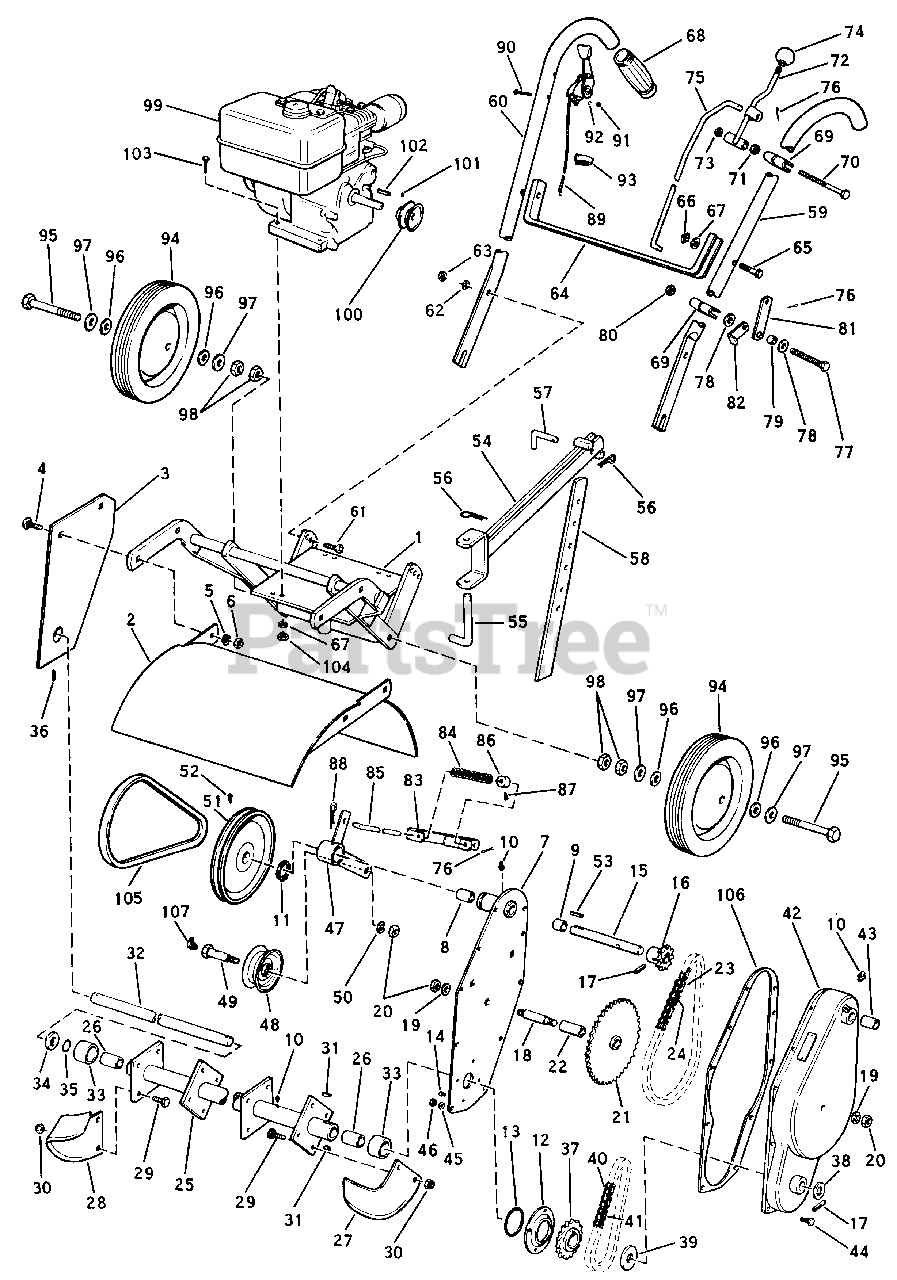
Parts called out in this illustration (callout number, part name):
1	Frame Assy.
2	Hood Assy.
3	Side Plate Assy.
4	Carriage Bolt 3/8-16 x 1 Lg.
5	Lockwasher 3/8
6	Hex Nut 3/8-16
7	Back Plate Assy.
8	Bushing
9	Bushing
10	Grease Fitting 1/4-28 St.
11	Snap Ring
12	Oil Seal Retainer
13	"O" Ring (Neoprene)
14	Self Tapping Screw #8-32 x 1/4 Lg.
15	Input Shaft
16	Input Sprocket & Hub Assy.
17	Roll Pin 3/16 x 1-1/8
18	Intermediate Shaft
19	Lockwasher 1/2 Shakeproof
20	Jam Nut 1/2-20
21	Sprocket Cluster Assy.
22	Bushing
23	Chain #41-1/2 Pitch, 55 Links
24	Connector Link #41-1/2 Pitch
25	Rotor Tube Assy.
26	Bushing
27	Tine RH
28	Tine LH
29	Tine Bolt
30	Marsden Nut 3/8-24
31	Woodruff Key
32	Rotor Shaft
33	Sleeve (Neoprene)
34	Thrust Washer
35	"O" Ring
36	Roll Pin
37	Sprocket 18 Tooth
39	Thrust Washer
40	Chain #40-1/2 Pitch, 37 Links
41	Connector Link #40-1/2 Pitch
42	Cover Assembly
43	Bushing
44	Capscrew 1/4-20 x 5/8 Lg.
45	Lockwasher 1/4 Shakeproof
46	Hex Nut 1/4-20
47	Idler Arm Assy.
48	Idler Pulley Assy.
49	Idler Pulley Shaft
50	Lockwasher 1/2
51	Pulley 7.4 OD x 5/8 Bore
52	Set Screw 5/16-18
53	Key 3/16 Sq. x 3/4 Lg.
54	Beam Assy.
55	Anchor Pin
56	Spring Clip
57	Selector Pin
58	Depth Bar
59	Handle Bar Assy. LH
60	Handle Bar Assy. RH
61	Capscrew 3/8-16 NC x 1-1/4 Lg.
62	Lockwasher 3/8
63	Hex Nut 3/8-16
64	Cross Brace
65	Capscrew 5/16-18 NC x 1-1/2 Lg.
66	Hex Nut 5/16-18
67	Lockwasher 5/16
68	Grip (Plastic)
69	Lock Collar
70	Idler Shaft Bolt
71	Jam Nut 3/8-24
72	Control Lever Assy. LH
73	Retaining Ring
75	Control Rod LH
76	Cotter Pin 3/32 x 3/4
77	Capscrew 3/8-24 x 2-1/2 Lg.
80	Hex Nut 3/8-24
81	Clutch Lever
82	Lever Stop
83	Spring Bracket Assy.
84	Control Spring
85	Transmission Control Rod
86	Set Collar
87	Set Screw 1/4-20
88	Spring Clip
89	Throttle Control Assembly
90	Machine Screw #8-32 x 1-1/2 Lg.
91	Hex Nut #8-32
92	Lockwasher #8
93	Cable Clip
94	Wheel Assy. 10 x 1.75
95	Hex Hd. Capscrew 1/2-13 NC x 4
96	Washer (Rubber)
97	Washer 1/2 SAE
98	Hex Jam Nut 1/2-13
99	Engine (B&S)
101	Set Screw 5/16-18 NC x 5/16 Lg.
102	Key 3/16 Sq. x 1-1/8
103	Capscrew 5/16-18 NC x 1-1/2 Lg.
104	Hex Nut 5/16-18
105	"V" Belt 37" A Section
106	Side Plate Gasket
107	Grease Fitting 1/4-28-90deg.
